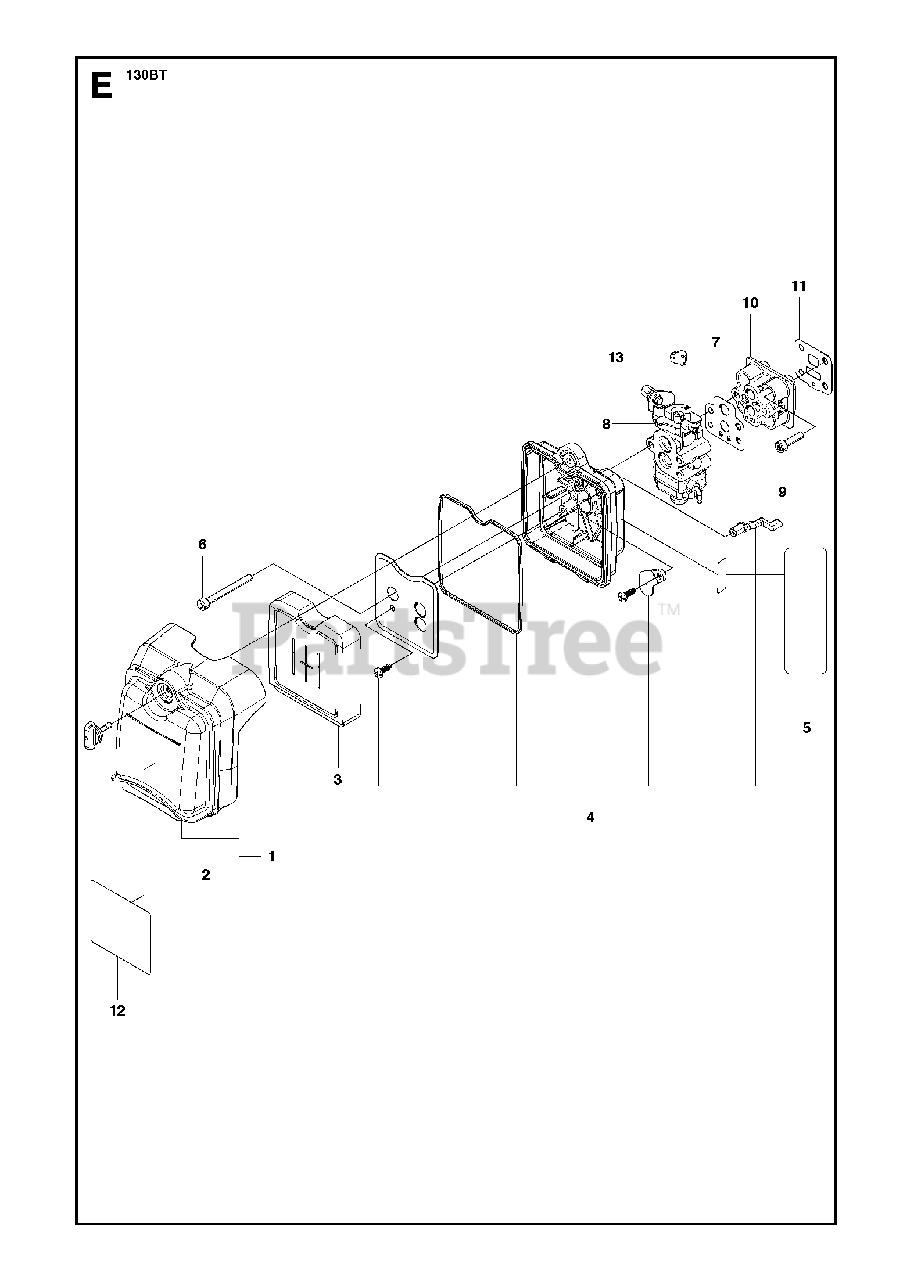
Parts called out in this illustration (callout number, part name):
2	KNOB
4	BODY AND SCREEN
8	CARBURETOR A
9	BOLT
11	GASKET INSULATOR
